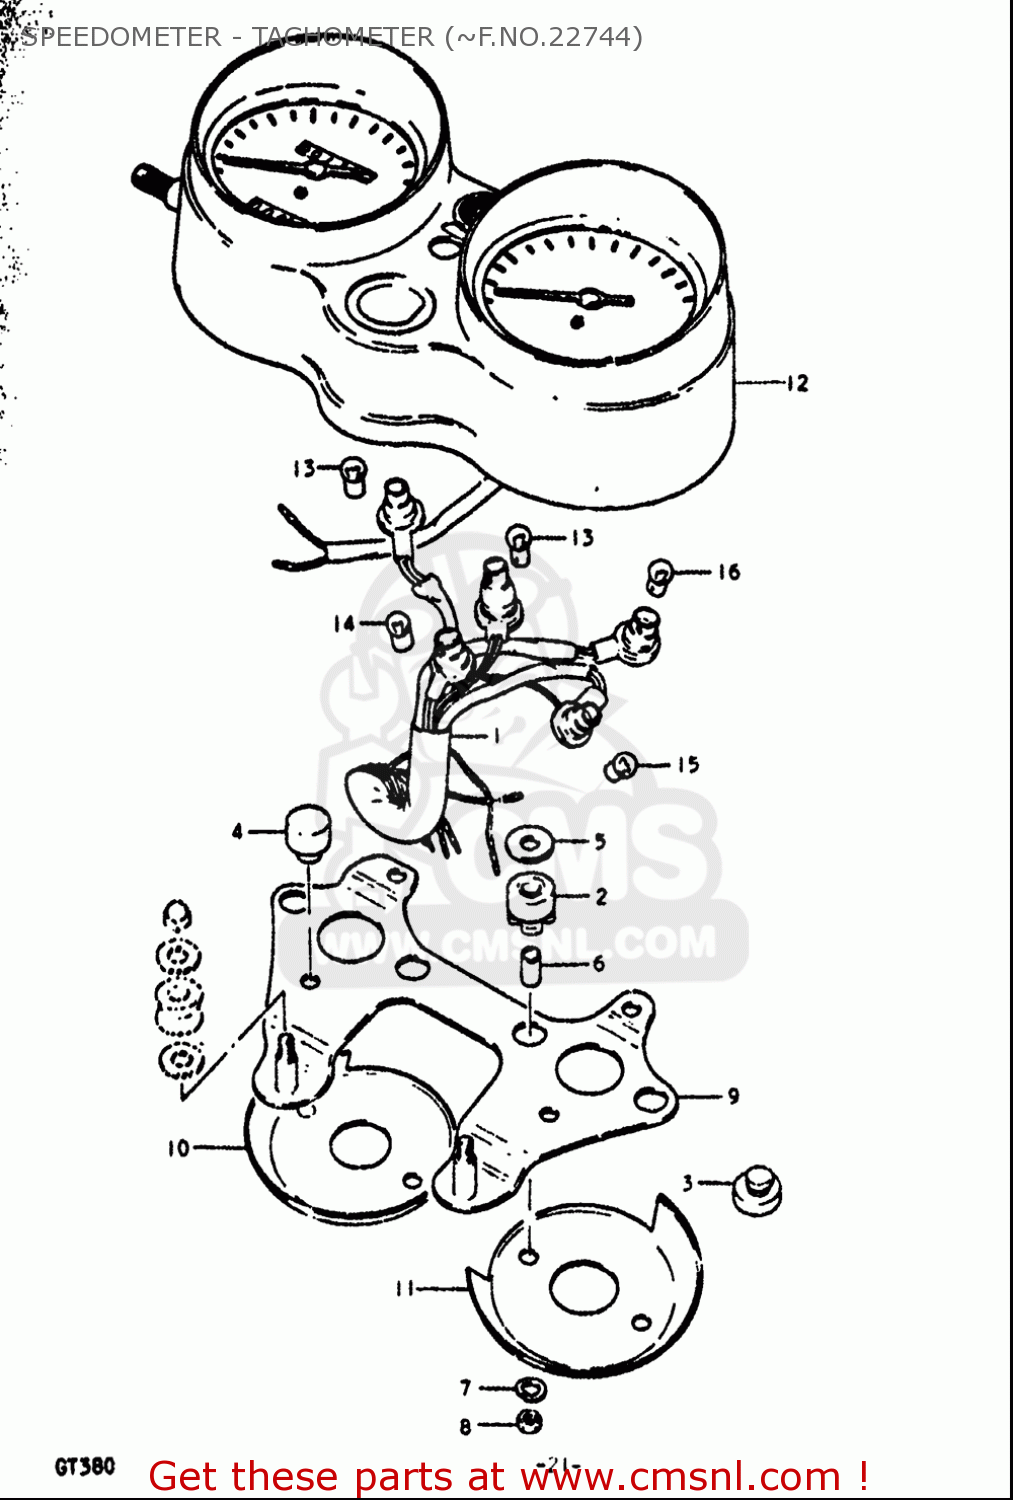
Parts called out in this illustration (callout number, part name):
2	CUSHION,METER NO.1
4	CUSHION,METER
7	WASHER,LOCK
8	NUT
13	BULB(12V3.4W,STANLEY,A72A)
16	BULB(12V1.7W,A71A)
